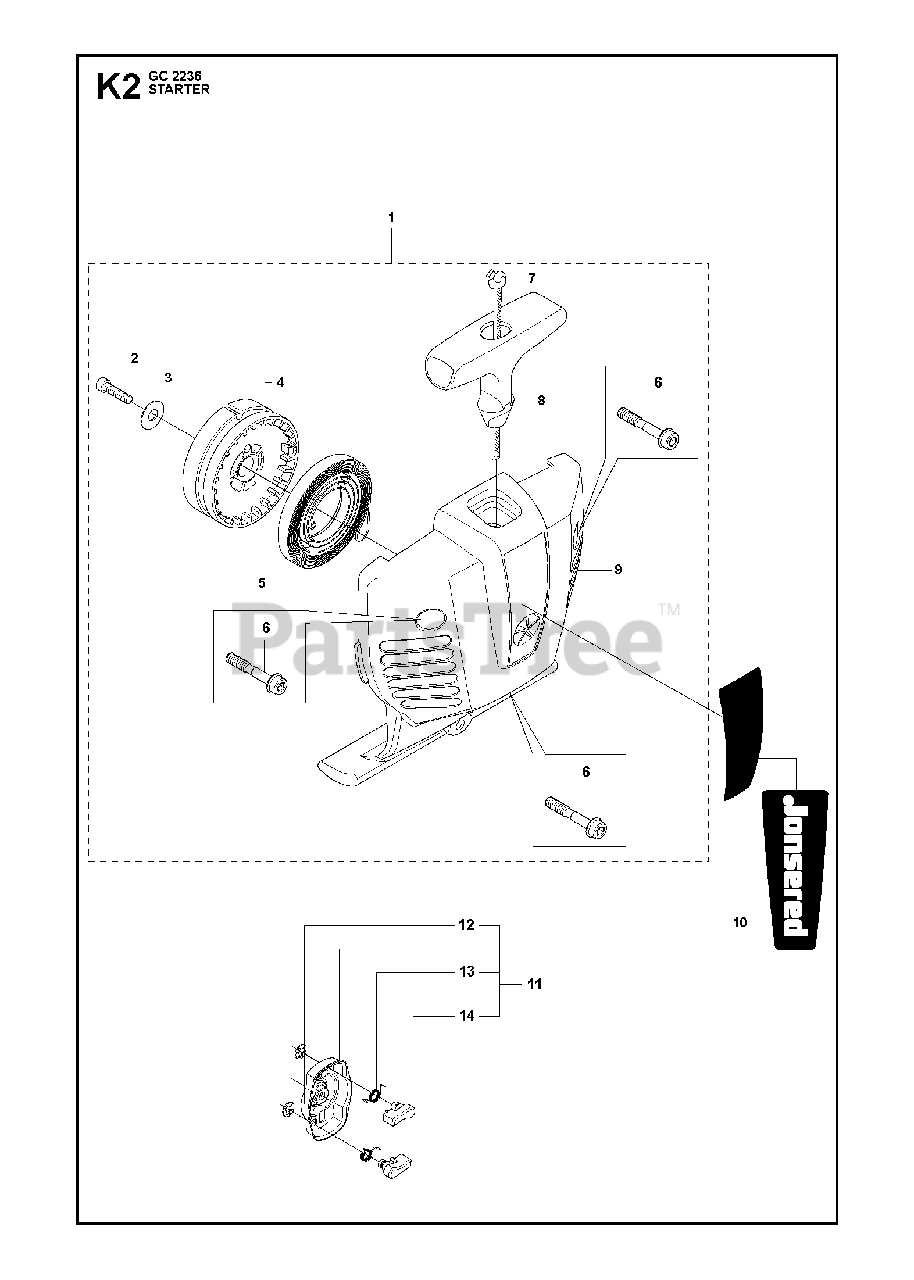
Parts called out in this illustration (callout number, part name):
1	STARTER HOUSING
2	SCREW
3	WASHER
4	%STARTER PULLEY
5	STARTER SPRING
6	SCREW IHSCFMO
7	STARTER ROPE
8	HANDLE
9	STARTER HOUSING
11	STARTER PAWL BRIDGE
12	E-RING 4
13	SPRING
14	STARTER PAWL
